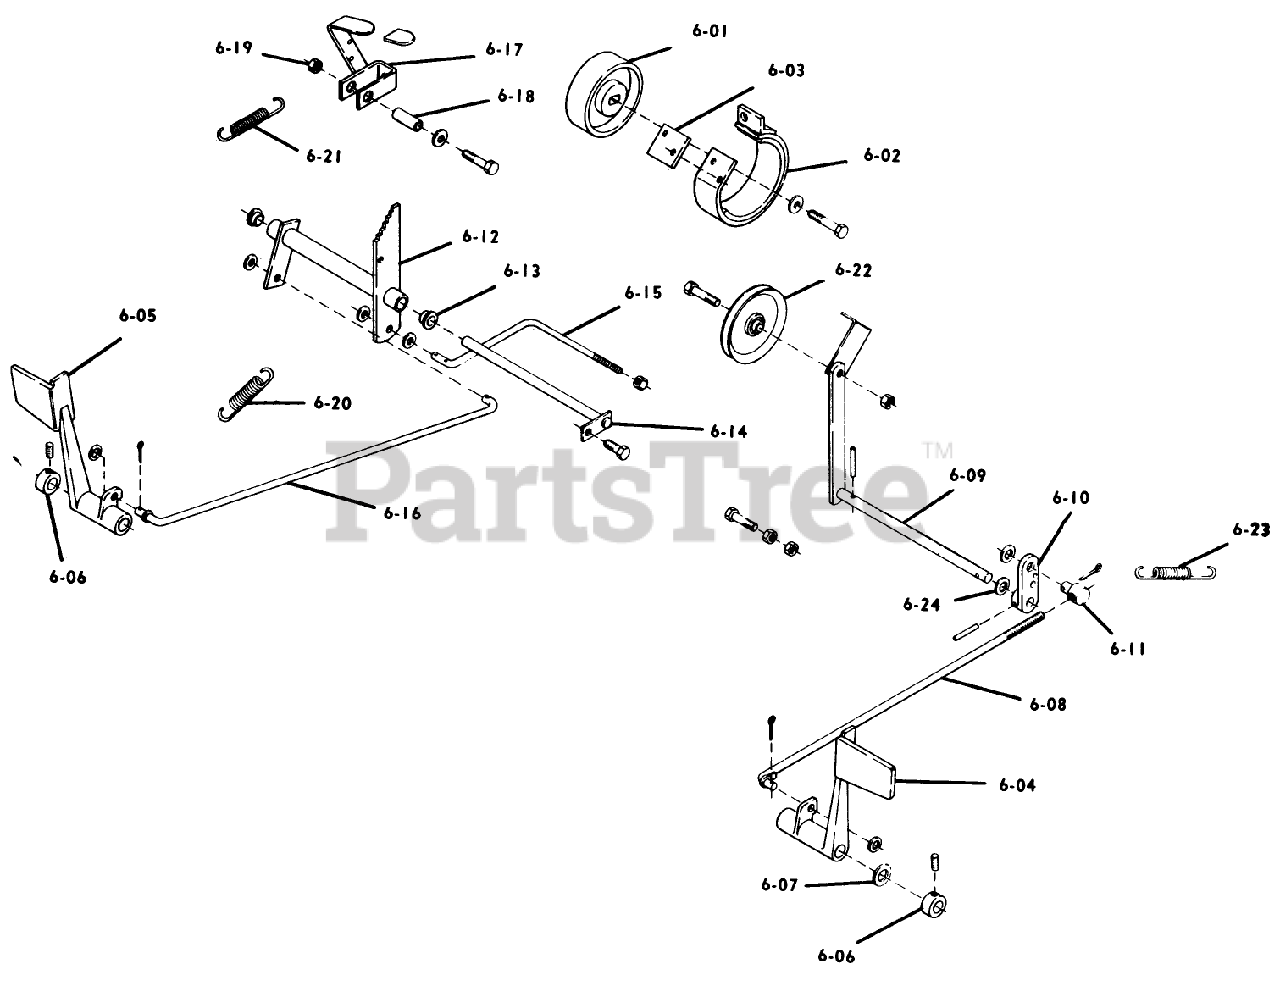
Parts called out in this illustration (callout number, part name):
6-01	Brake Drum
6-02	BRAKE BAND ASM
6-03	Plate-Stop
6-04	Clutch Pedal
6-05	PEDAL-BRAKE R
6-06	Collar
6-07	WASHER-BOWED
6-08	ROD AND GUIDE ASM
6-09	Idler Arm Assembly
6-10	Clutch Pivot Arm
6-12	Bellcrank Assy
6-13	BUSHING-FLANGED
6-14	Rod Assy
6-15	Brake Rod
6-16	Rod
6-17	Brake Lever Assy
6-18	SPACER
6-19	LOCKNUT-FLANGE
6-20	Spring
6-21	SPRING-EXTENSION
6-22	PULLEY-IDLER
6-23	Spring
